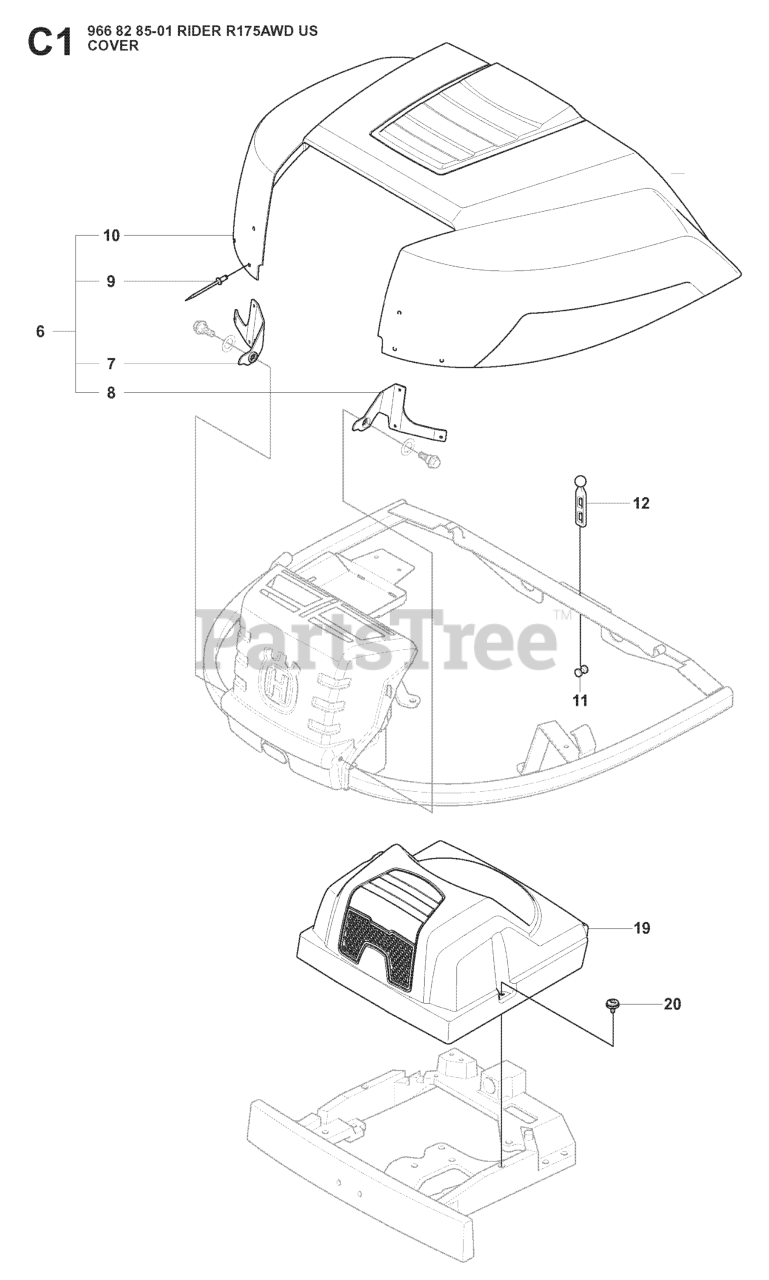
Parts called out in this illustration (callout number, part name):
6	ENGINE HOOD ASSY
10	ENGINE HOOD ASSY
12	Support Strap
19	COVER
